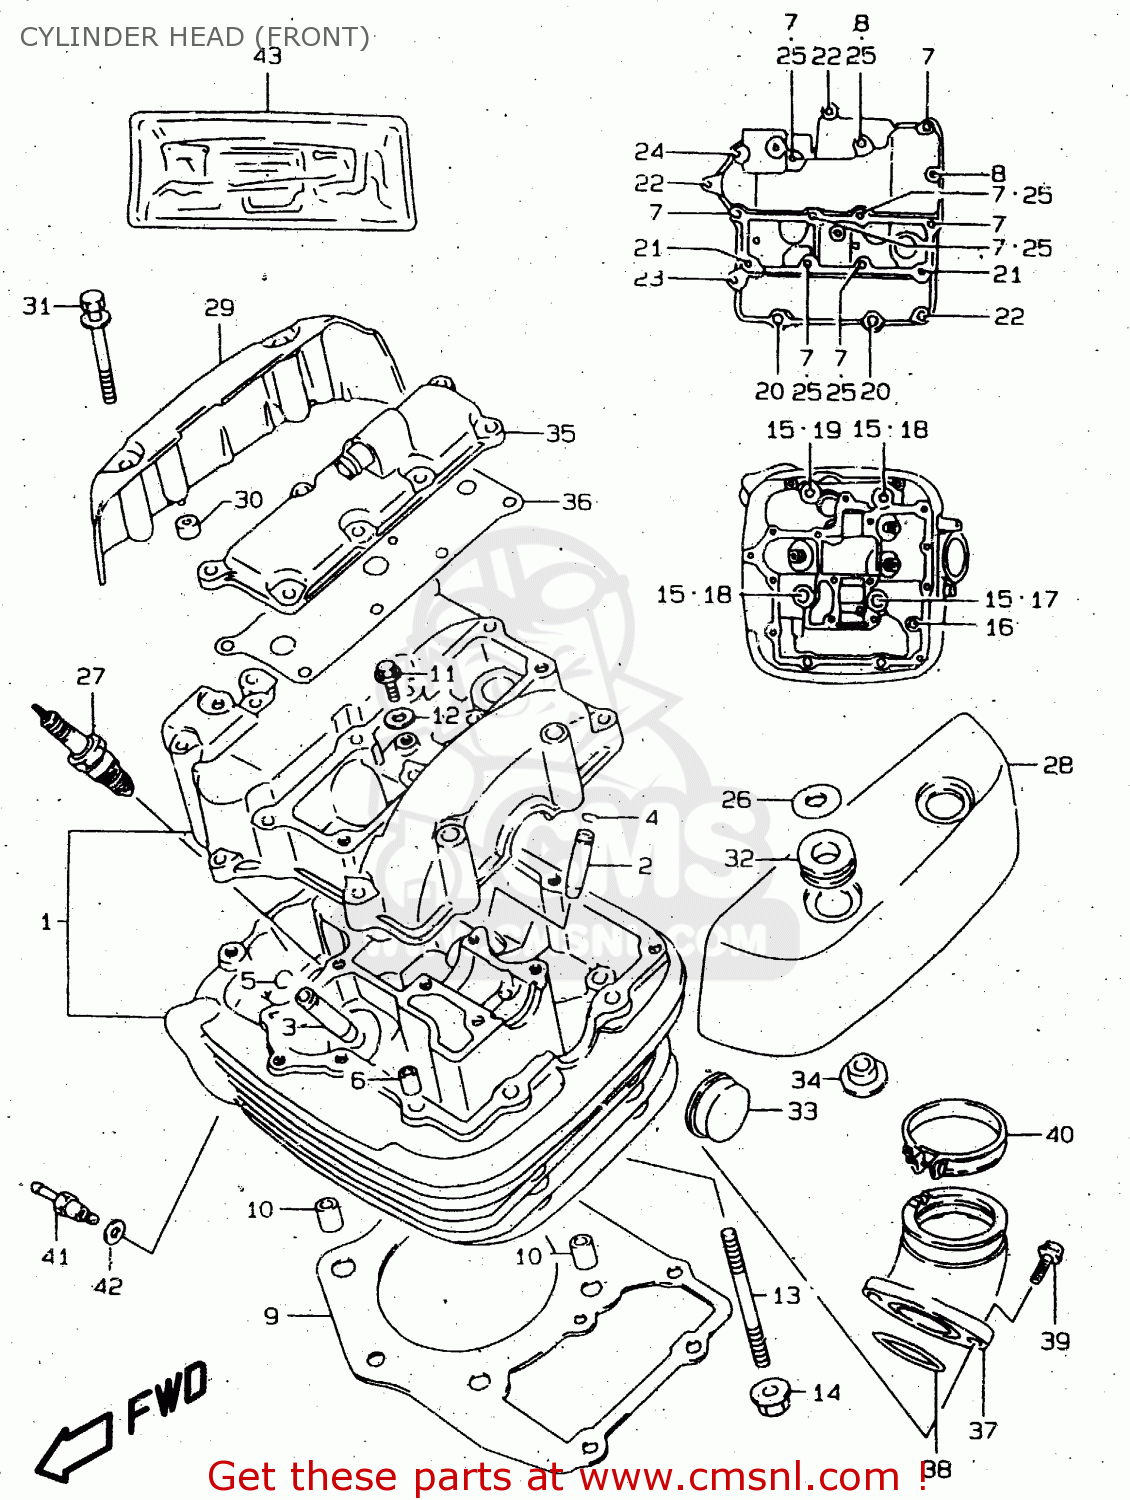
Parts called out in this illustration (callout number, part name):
1	HEAD ASSY,CYLINDER FR
2	GUIDE,INTAKE VALVE
3	GUIDE,INTAKE VALVE
4	RING,SNAP
5	RING,SNAP
6	PIN(6.2X8X11)
7	BOLT(6X60)
8	BOLT(6X55)
9	GASKET,CYLINDER HEAD FR (NAS)
10	PIN
11	BOLT
12	GASKET(6.2X13X1.2) (NAS)
13	BOLT,STUD
14	NUT
15	WASHER (10.5X22X2.3)
16	BOLT(8X70)
17	BOLT(10X180)
18	BOLT(10X190)
19	BOLT(10X200)
20	BOLT(8X268)
21	BOLT
22	BOLT
23	BOLT
24	BOLT
25	GASKET(5.8X13X1.2) (NAS)
26	WASHER(8.5X24X1.6)
27	SPARK PLUG DP7EA-9
28	CAP,CYLINDER HEAD COVER FL
29	CAP,CYLINDER HEAD COVER FR
30	CUSHION,R CAP
31	BOLT
32	CUSHION
33	PLUG(OD:30)
34	BUSH
35	COVER,BREATHER
36	GASKET,BREATHER COVER (NAS)
37	PIPE ASSY,INTAKE FR
38	O RING(D:2.4,ID:41.7)
39	BOLT
40	CLAMP
41	BOLT UNION
42	GASKET(6.2X13X1.2) (NAS)
43	GASKET SET (NAS)
